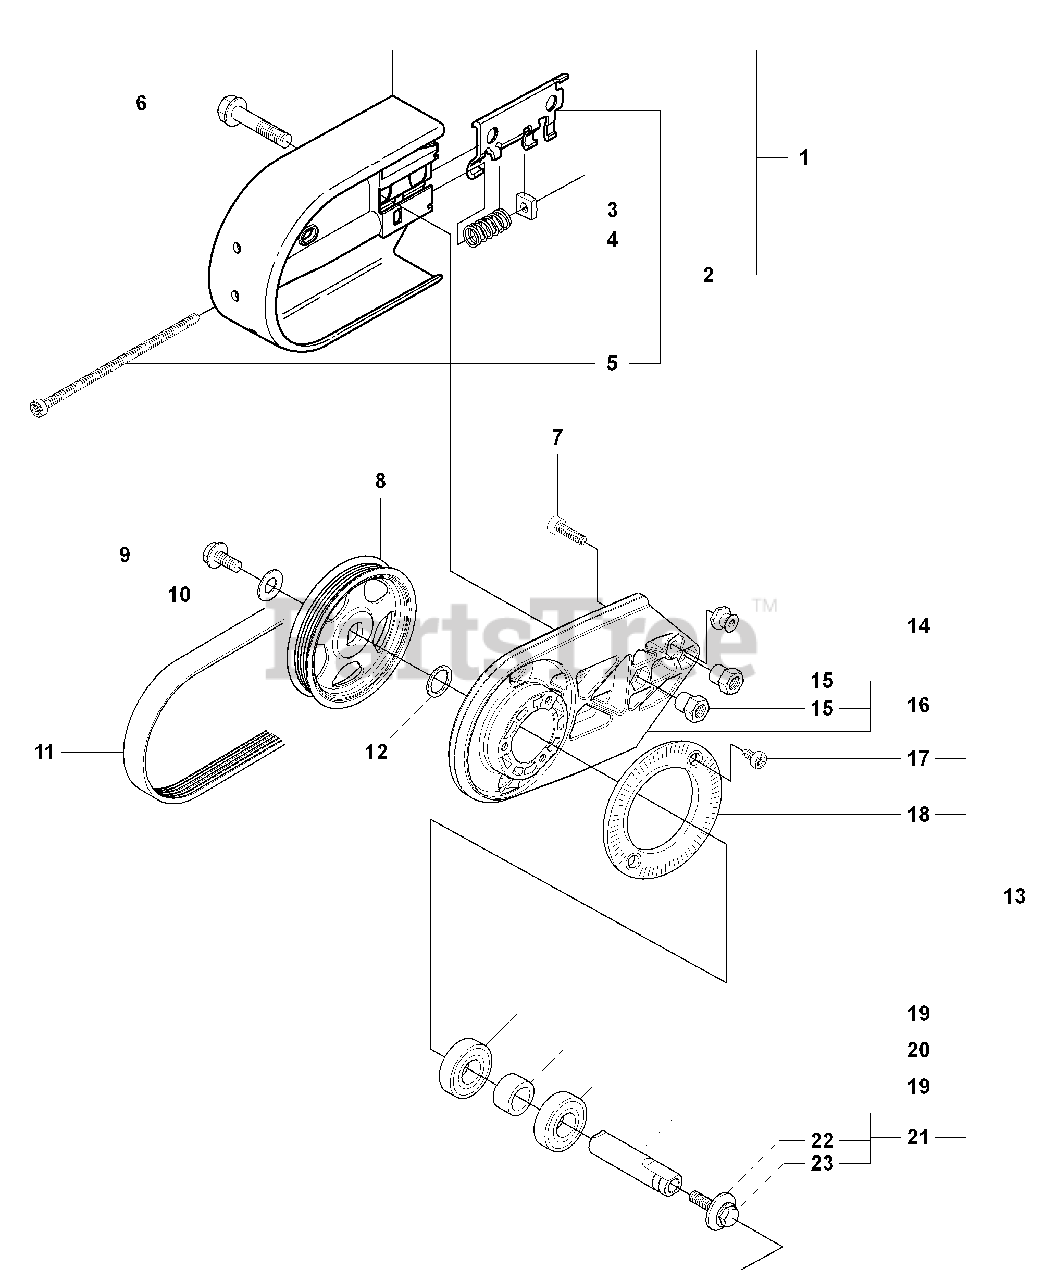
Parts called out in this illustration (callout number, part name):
1	BELT GUARD
2	BELT TENSIONER ASSY
4	COMPRESSION SPRING
5	SCREW
6	COLLAR SCREW
8	PULLEY
9	SCREW COLLAR
10	WASHER STEEL
12	WASHER STEEL
13	BEARING HOUSING
14	TORSION STOP
16	BEARING HOUSING
18	SCREEN PATTERN FLANG
19	BALL BEARING
20	SPACING SLEEVE
21	SHAFT
22	WASHER
23	COLLAR SCREW
